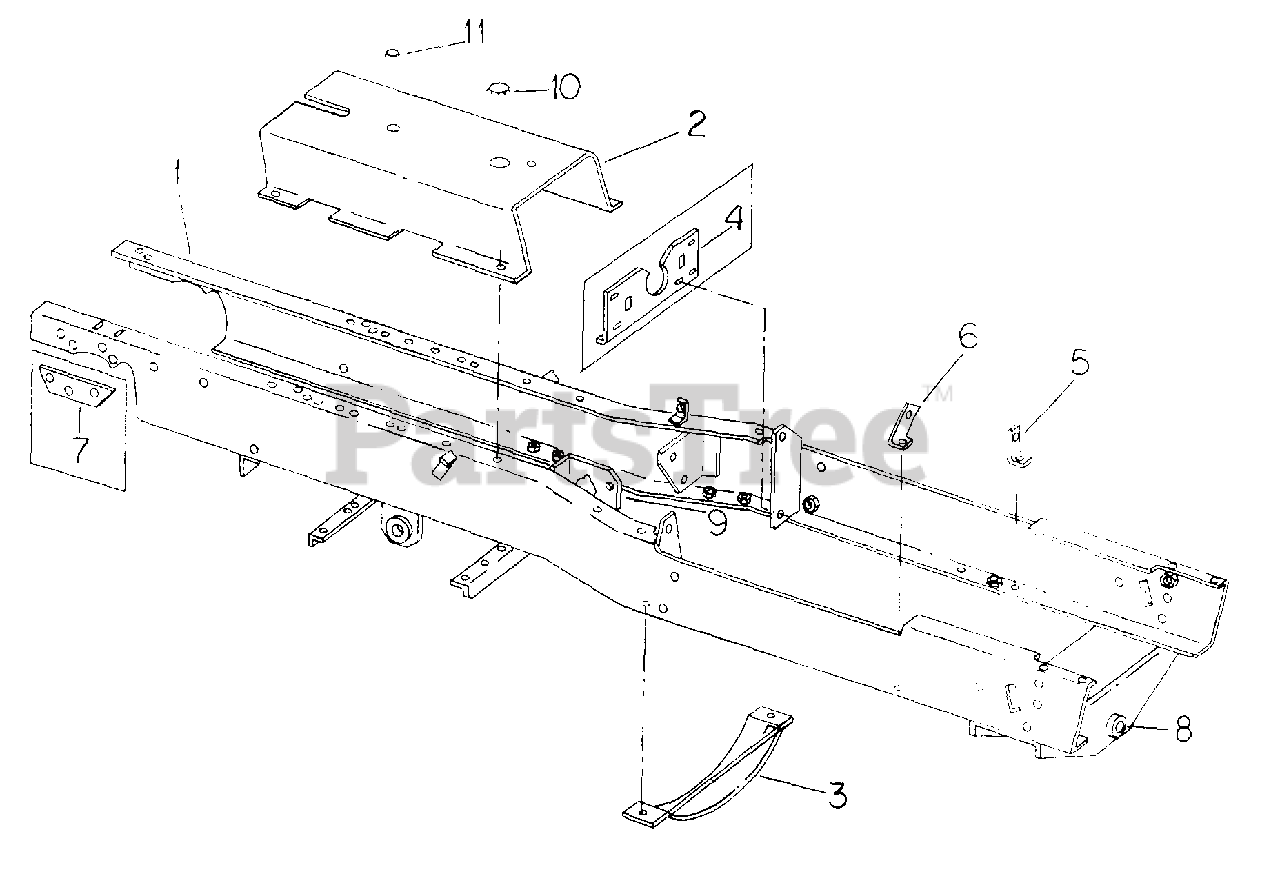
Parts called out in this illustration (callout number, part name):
1	FRAME ASSY
2	COVER, FRAME TOP
3	SHIELD, ASSY, FLYWHEEL
4	SUPPORT, FRONT CLUTCH MAIN SHAFT BRG
5	ANGLE ASSY, ENGINE BRACKET LH
6	ANGLE ASSY, ENGINE BRACKET RH
7	BLOCK, REINFORCEMENT
8	HUB, FRONT AXLE PIVOT PIN FRONT
8	HUB, FRONT AXLE PIVOT PIN REAR
9	SUPPORT, STEERING GEAR
10	PLUG, 1-1/4 IN. BUTTON
11	PLUG, 7/8 IN. BUTTON
